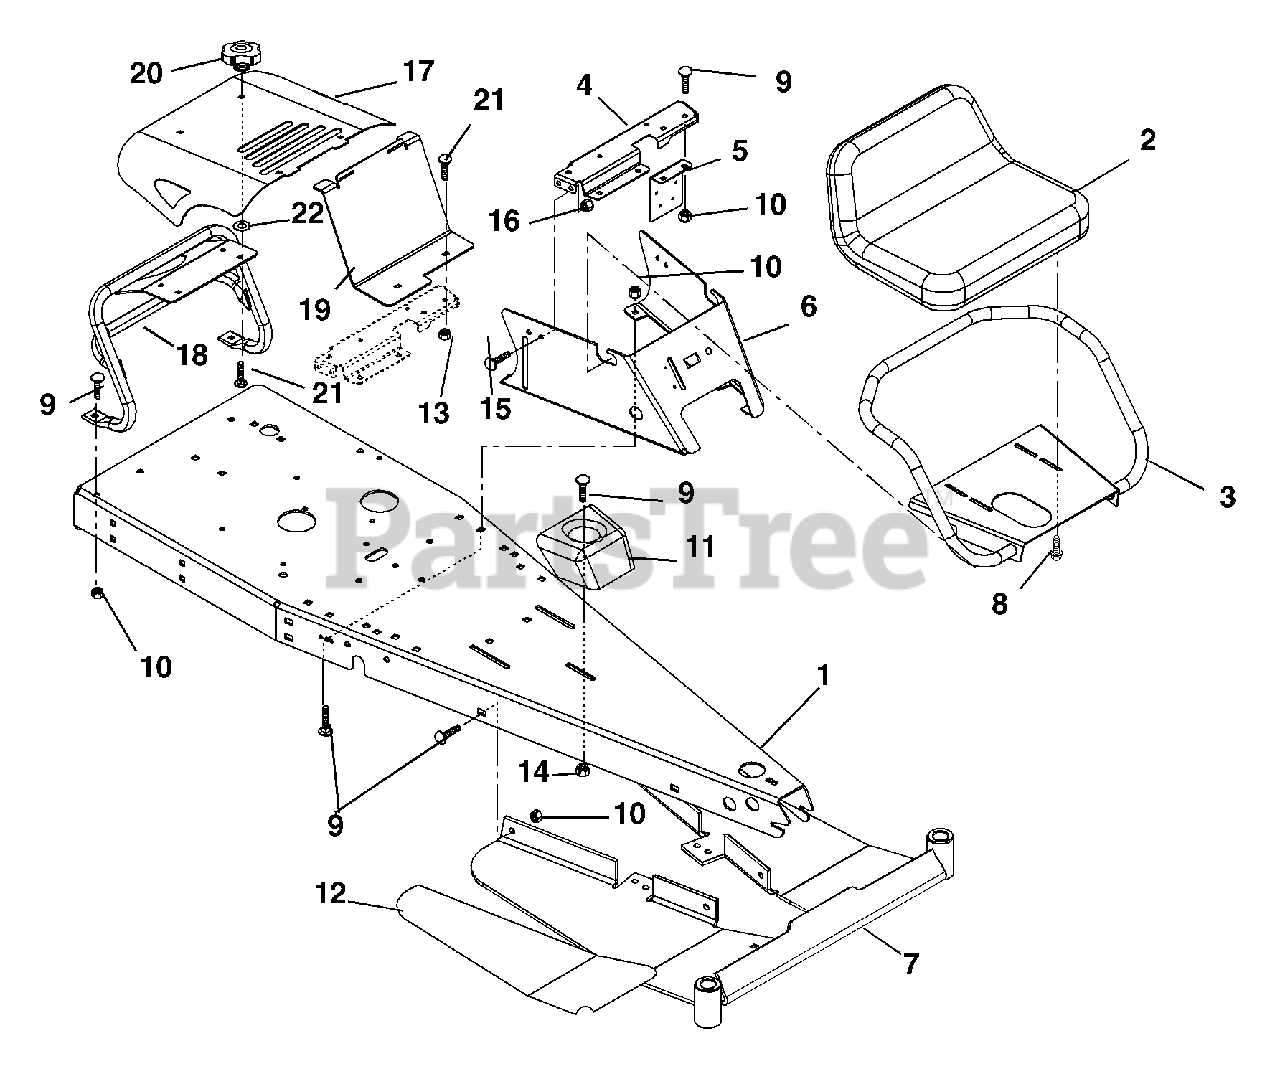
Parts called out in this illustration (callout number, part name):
2	Seat V-1300 Low Weltless
3	Weldment, Seat Mount/Bar
4	Reforcement, Seat Support
5	Panel, Solenoid Mounting
6	Seat Support
7	Weldment, Footrest
8	Bolt, Serrated Hex Flange Washer Head .312-18 x .75
9	Bolt, Round Head Square Neck .31-18 x .75 Grade 5
10	Nut, Top Lock Nut Locking Top Flange .38-16
11	Cupholder
12	Grip, Rear Engine Rider Footrest Left Hand
12	Grip, Rear Engine Rider Footrest Right Hand
13	Nut, Locking Top Flange .31-18
14	Nut, Spin Lock Flange .312-18
15	Screw, Machine .25-20 x .75
16	Nut, Retainer .25-20 x .56
17	Engine, Hood
18	Weldment Tube
19	Bracket, Hood Support
20	Knob, Clamping .31-18 Nyloc
21	Bolt, Round Head Square Neck .31-18 x 1.00
22	Nut, Push .312
